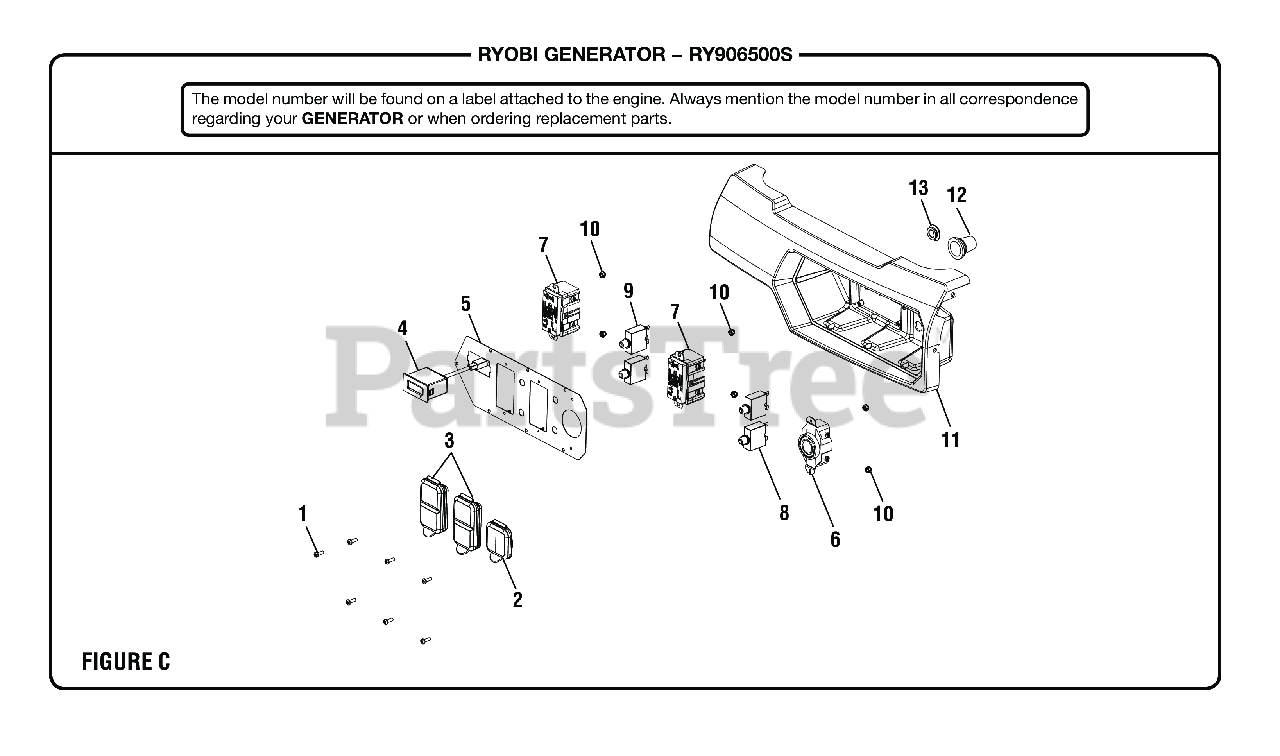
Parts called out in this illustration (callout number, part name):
1	Screw (#8-18 x 1/2 in., T20 Torx Pan Hd.)
2	240 Volt ReceptacleRain Cover
3	120 Volt Receptacle Rain Cover
4	Digital Display
5	Front Panel
6	Twist Lock Recepticle (120/240 Volt, 30 Amp, L14-30)
7	120 Volt Duplex GFCI Receptacle
8	Circuit Breaker (27 Amp)
9	Circuit Breaker (20 Amp, 125 Volt)
10	Lock Nut (M4)
11	Control Box (Back Panel)
12	Wiring Rubber Boot
